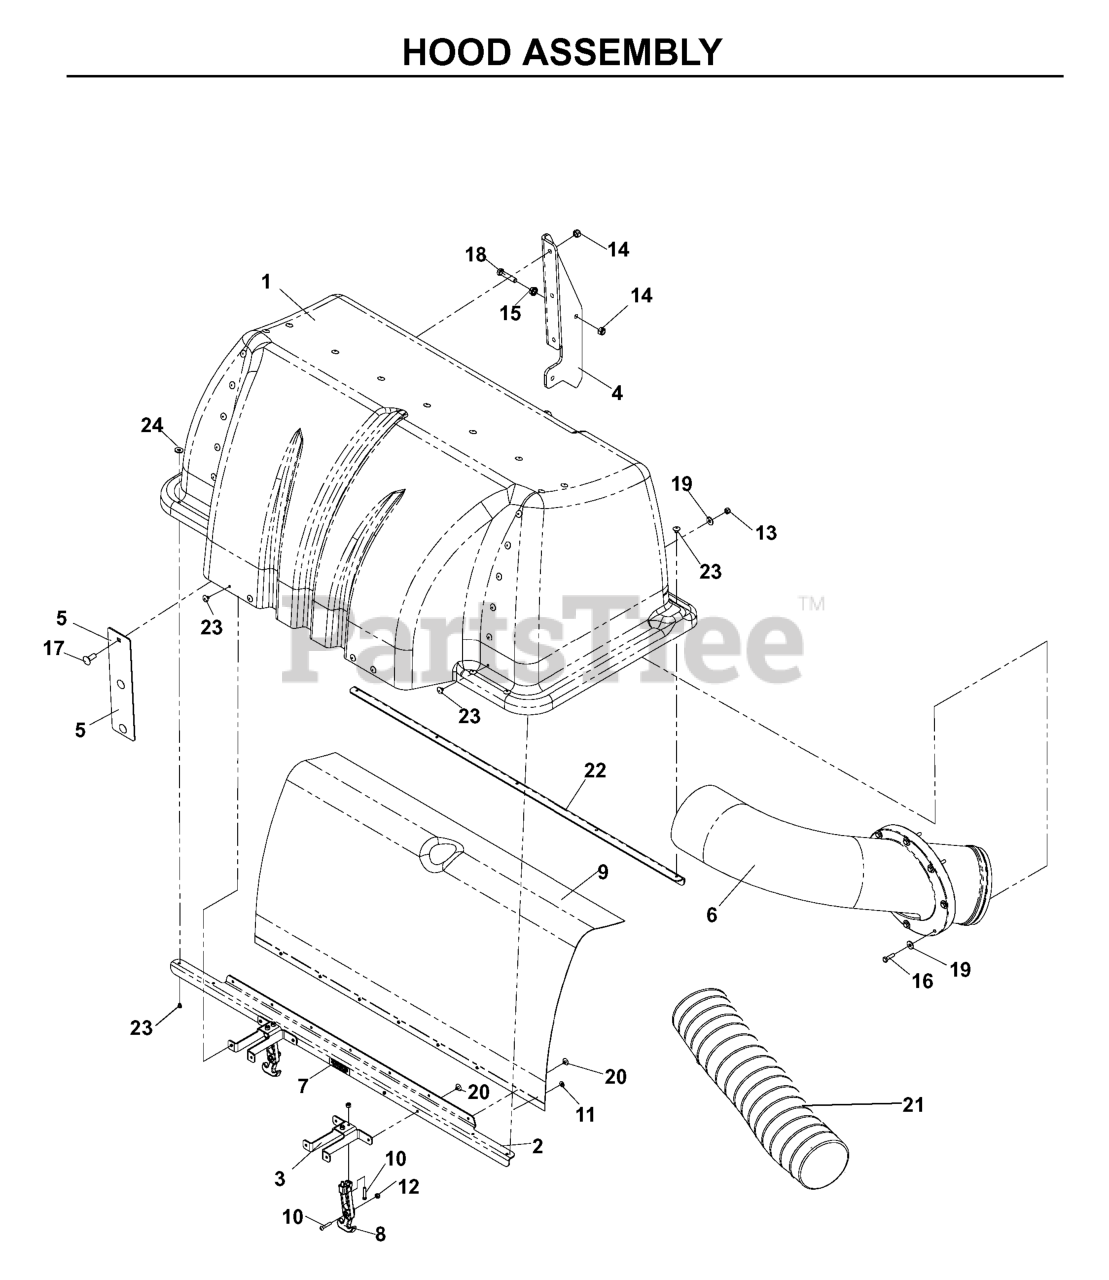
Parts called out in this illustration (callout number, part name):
2	HOOD SUPPORT
3	SUPPORT, DRAW LATCH
4	HOOD HINGE
5	MOUNT PLATE
7	DECAL, VENTILATION
8	DRAW LATCH, FLEXIBLE T-HANDLE
9	MESH, POLY DIAMOND
10	SCR, #10-24 X 1-1/8
11	WASHER #10
12	NUT 10-24 NYLOC
13	NUT.1/4-20.HEX.NYLOC.ZD
14	NUT 3/8-16 NYLOC
15	NUT 3/8C WHIZ
16	BOLT 1/4C X 1 3/4
17	RHSNB 3/8C X 1
18	HCS 3/8-16 X 1 3/4 GR5
19	WASHER 1/4 FLAT
20	RIVET E/16 X 1/4 LG FLG
21	HOSE 7 X 58 CLEAR
22	HOOD SUPPORT, REAR
23	RIVERT, 3/16, STAVEX
24	WASHER, #10 MACH SCR BLK OX
539111314	HOSE 7 X 54 CLEAR
